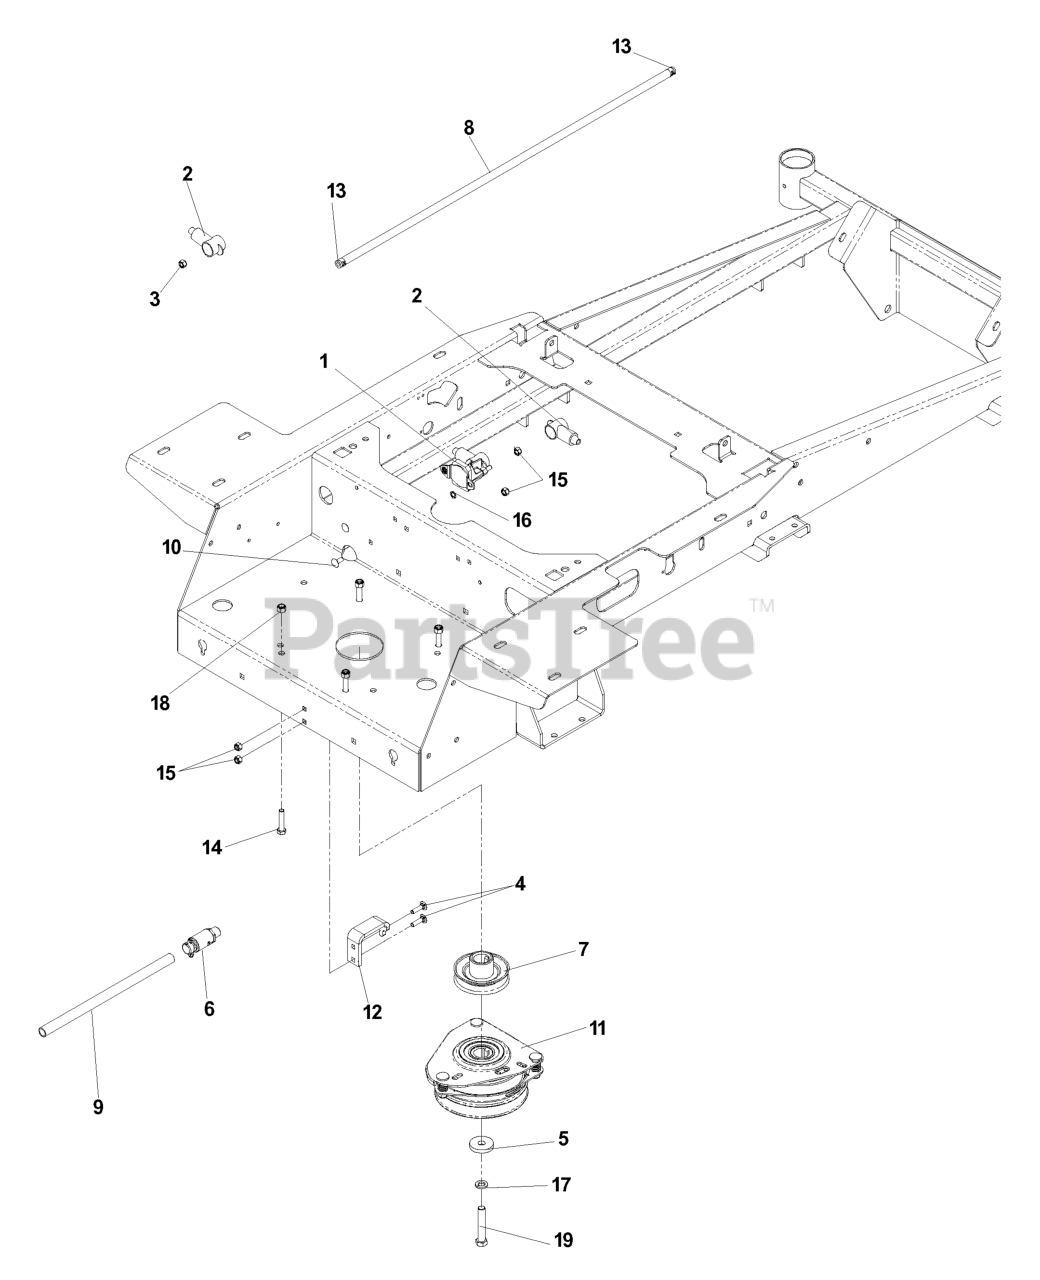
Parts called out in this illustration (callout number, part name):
3	JAM NUT 1/4C (2 2 PW01)
4	RHSNB, 1/4-20 X 1, GR5
5	CLUTCH, WASHER
6	OIL DRAIN FITTING
8	FUEL LINE 24"
9	FUEL LINE 5"
10	RHSSNB, 1/4-20X5/8
12	CLUTCH TIE DOWN
13	HOSE CLAMP
14	CAPSCREW 5/16 X 1/1/2 HEX HEAD
15	NUT.1/4-20.HEX.NYLOC.ZD
16	WASHER 1/4 INT TOOTH
17	WASHER 7/16 LOCK
18	NUT 5/16 NYLOC
19	BOLT 7/16F X 2 1/2
